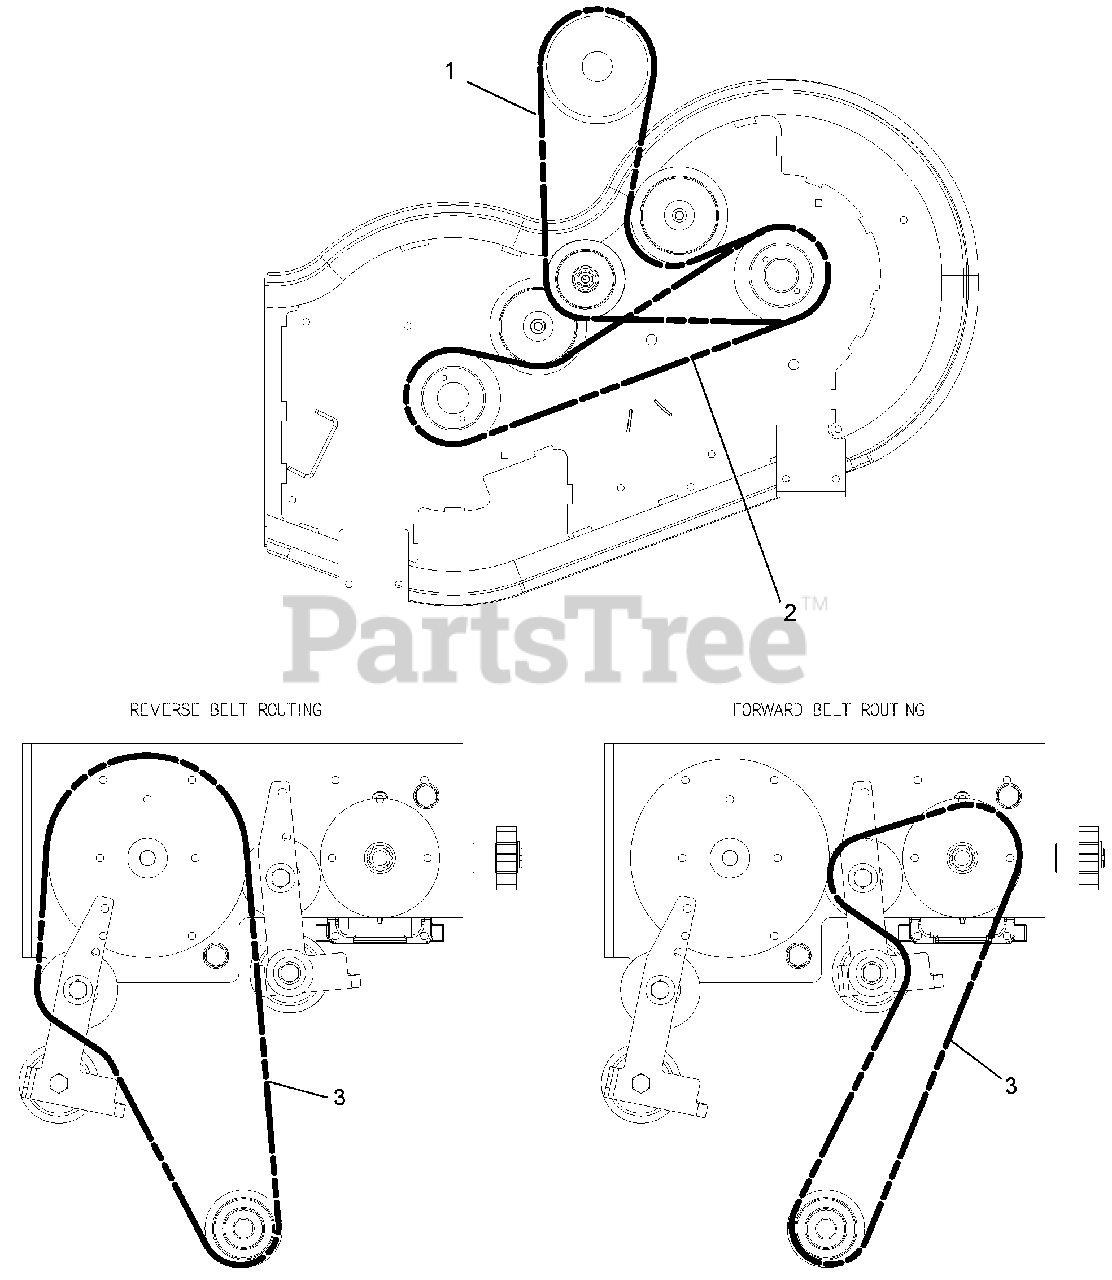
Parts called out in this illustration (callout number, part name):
1	V-BELT, HA-WRAPPED
2	V-BELT, HA-WRAPPED
3	V-BELT, 3L-WRAPPED
